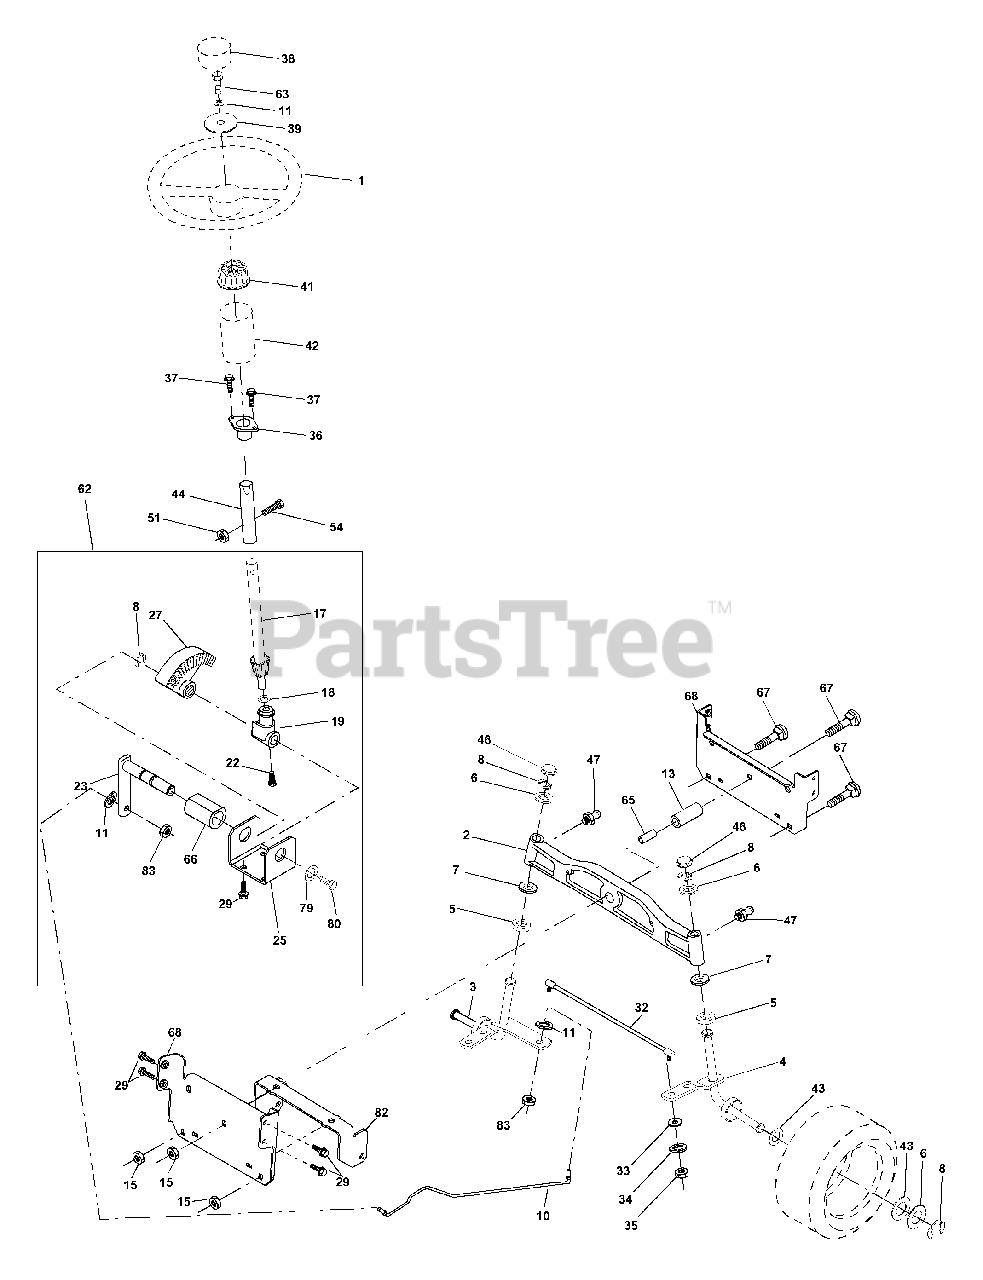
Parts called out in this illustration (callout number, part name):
1	Wheel Steering
2	Axle Cast Lt Machined
3	Spindle Asm LH
4	Spindle Asm RH
5	Bearing Race Thrust Harden
6	Washer 25/32 X 1-5/8 X 16 Ga
7	Washer 27/32 X 1-1/4 X 16 Ga
8	Ring Klip #t5304-75
11	Washer Lock Hvy Hlcl Spr 3/8
13	Spacer Brg Axle Front
15	Nut Hex Flange Lock
17	Shaft Asm Strg
18	Washer Thrust 515x 750x 033
19	Support Shaft
22	Screw Hex Wshhd Torx
23	Shaft Asm Pittman
25	Bracket Steering
27	Gear Sector
29	Screw 3/8-16x3/4
32	Rod Tie Ball J
33	Washer 11/32 x 3/4 x 16 Ga.
34	Washer Lock Hvy Helical 5/16
35	Nut Crown Lock 5/16-18
36	Bushing Strg
38	Insert Cap Strg Wh
39	Washer 13/32 x 1-1/20 x 11 Ga
41	Adaptor Wheel Strg
42	Boot Steering Shaft
43	Washer 25/32 X 1 1/4 X 16 Ga
44	Extension Steering Shaft LR/LT
46	Cap Spindle Fr Top Blk
47	Fitting Grease
51	Nut Lock Hex w/Ins 5/16-18
54	Bolt Fin Hex 5/16-18 Unc x 1-1/4
62	Kit, Steering Assembly Svc
63	Bolt Fin Hex 3/8-16unc x 1 Gr. 5
65	Spacer Brace Axle
66	Bearing Arm Pittman
67	Bolt Rdhd Sqnk 3/8-16 x 2-1/4
68	Axle, Brace
79	Washer 13/32 x 1-1/4 x 12 Ga
80	Bolt Hex Nylon 3/8-16 x 3/4
82	Bracket Susp Chassis Front
83	Lock nut
